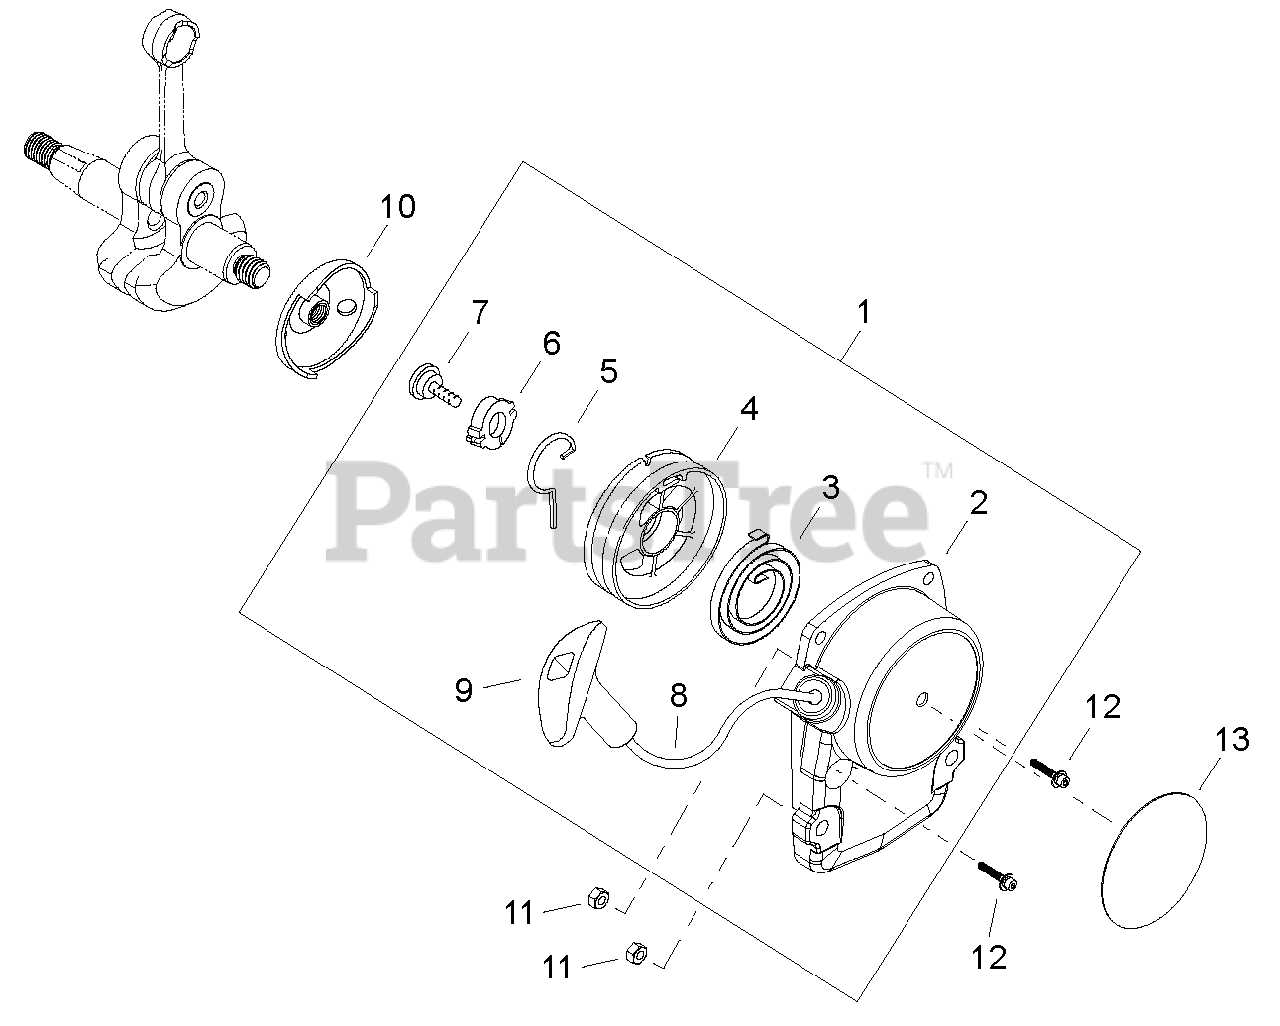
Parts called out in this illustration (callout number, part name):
2	CASE, RECOIL STARTER
3	SPRING, RECOIL
4	REEL, ROPE
4-1	STARTER ASSY, RECOIL
5	ARM, SWING
6	WASHER 5
7	SCREW 5
8	ROPE, STARTER
9	GRIP, STARTER
10	PULLEY, STARTER
11	NUT M5
12	BOLT M4×16
13	LABEL, AH242
